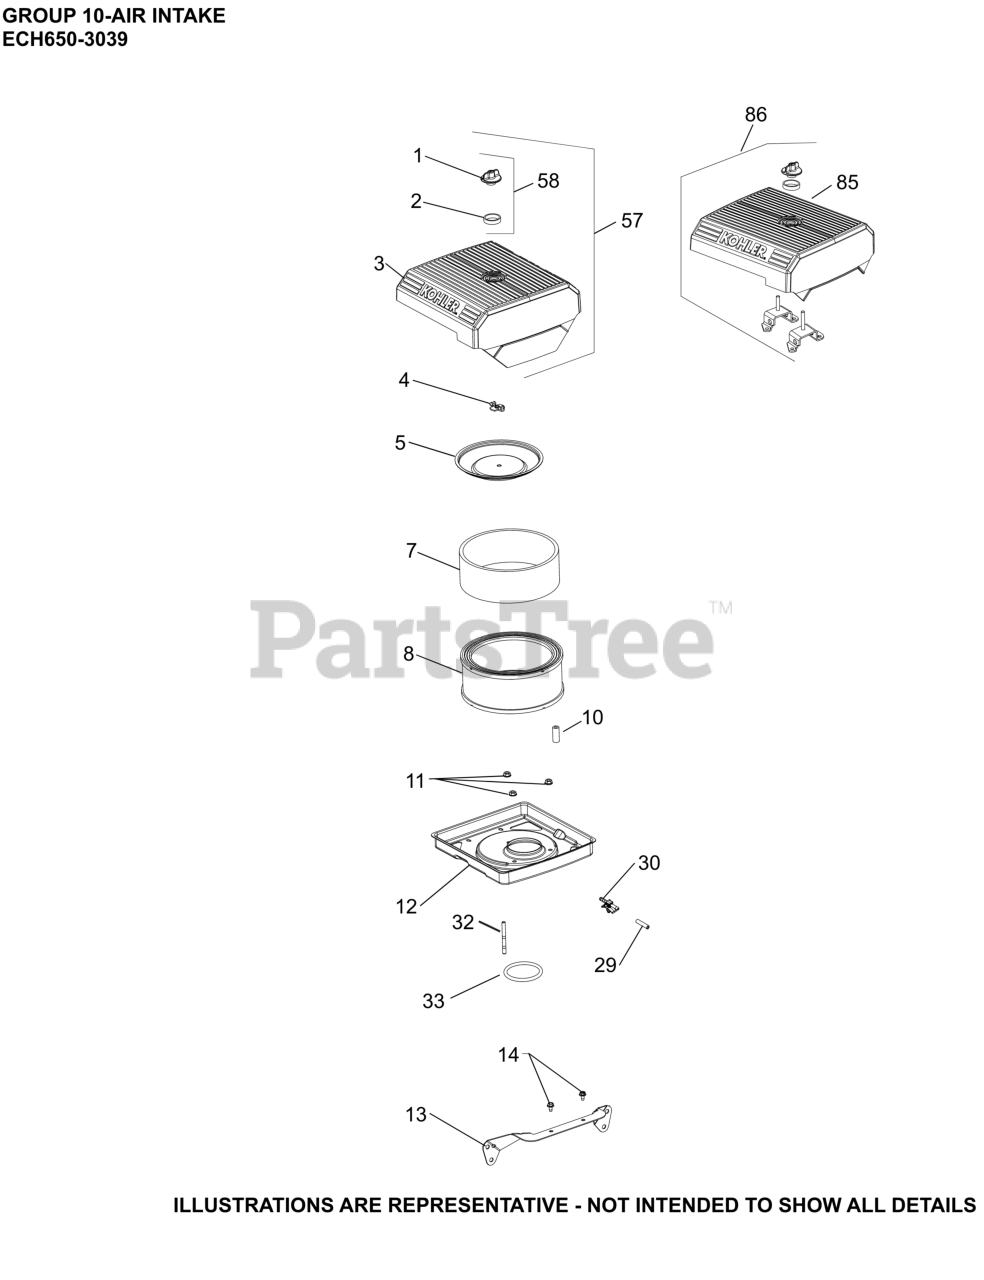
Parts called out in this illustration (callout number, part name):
1	KNOB, COVER
3	COVER, AIR CLEANER
4	NUT, WING
5	COVER, INNER AIR CLEANER
7	PRE CLEANER LOW ELEMENT
8	ELEMENT, AIR CLEANER
11	NUT, FLG M6X1.0
12	BASE, AIR CLEANER
13	AIR CLEANER BRACKET
14	SCREW, THREAD FORMING
29	CAP, MASKING
30	CONNECTOR, EVAPORATIVE
32	STUD, LOW PROFILE A/C
33	O-RING, AIR CLEANER BASE
57	KIT, AIR CLEANER COVER
58	KIT, KNOB W/SEAL
NI	COVER, AIR CLEANER
NI	KIT, AIR CLEANER COVER
